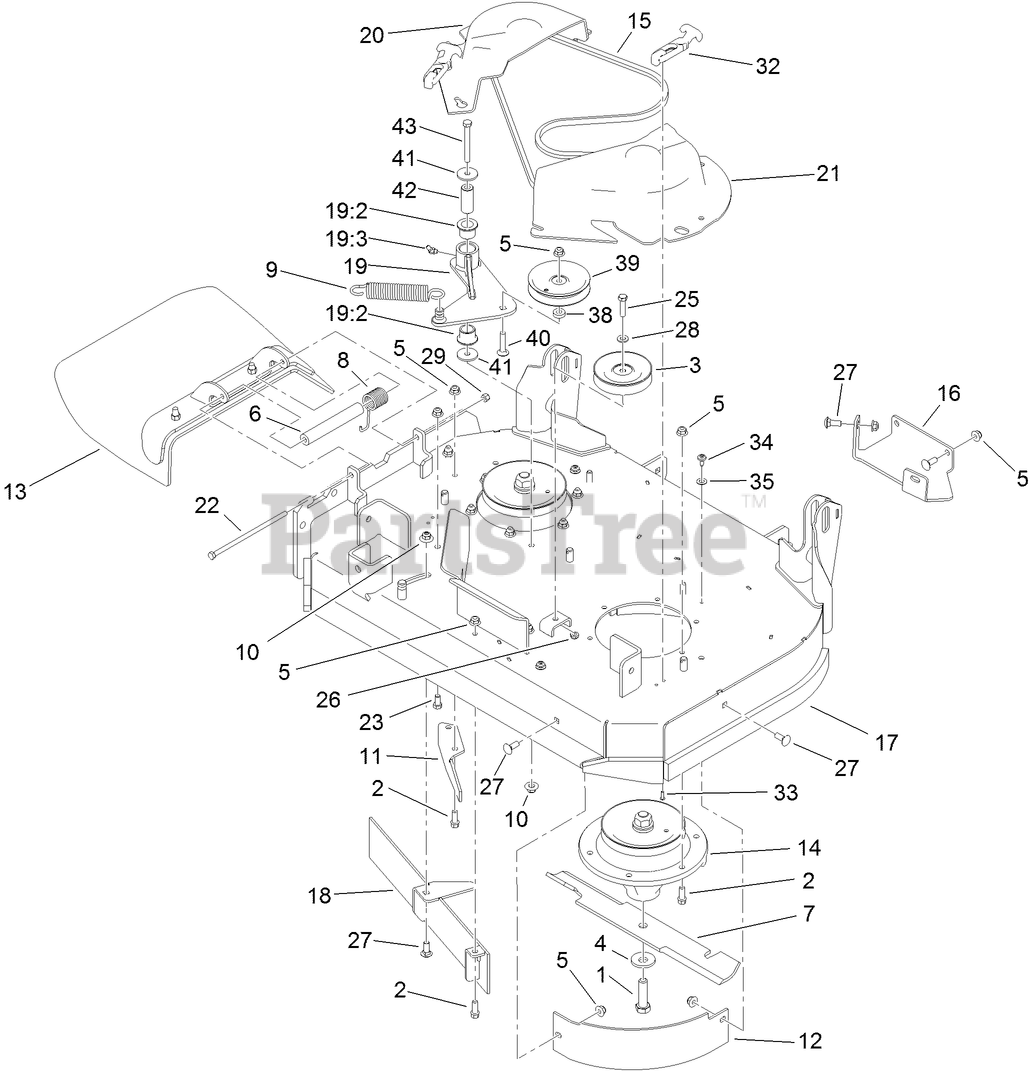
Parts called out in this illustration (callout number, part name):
1	SCREW-BLADE
2	SCREW-HWH
3	PULLEY-IDLER
4	Washer-Blade Bolt, Heavy
5	NUT-HF, NI
6	SPACER
7	BLADE-18IN, HI FLOW
8	SPRING-TORSION
9	SPRING-EXTENSION
10	NUT-FLANGE, NI
11	BAFFLE-DISCHARGE
12	BAFFLE-FRONT, LH
13	DEFLECTOR ASM
14	SPINDLE ASM
15	BELT-V
16	PLATE-SKID
17	DECK AND DECAL ASM
18	FRONT BAFFLE ASM
19	IDLER ARM ASM
19:2	BUSHING
19:3	FITTING-LUBE, 45 DEG
20	COVER-BELT, RH
21	COVER-BELT, LH
22	SCREW-HH
23	SCREW-HH
25	SCREW-HH
26	NUT-LOCK, NI
27	BOLT-CARR
28	WASHER-FLAT
29	NUT-LOCK, NI
32	LATCH-RUBBER
33	SCREW-HSBH
34	SCREW-SHOULDER
35	WASHER-THRUST
38	SPACER
39	PULLEY-IDLER
40	SCREW-CARR
41	WASHER
42	SPACER-PLAIN
43	SCREW-HH
